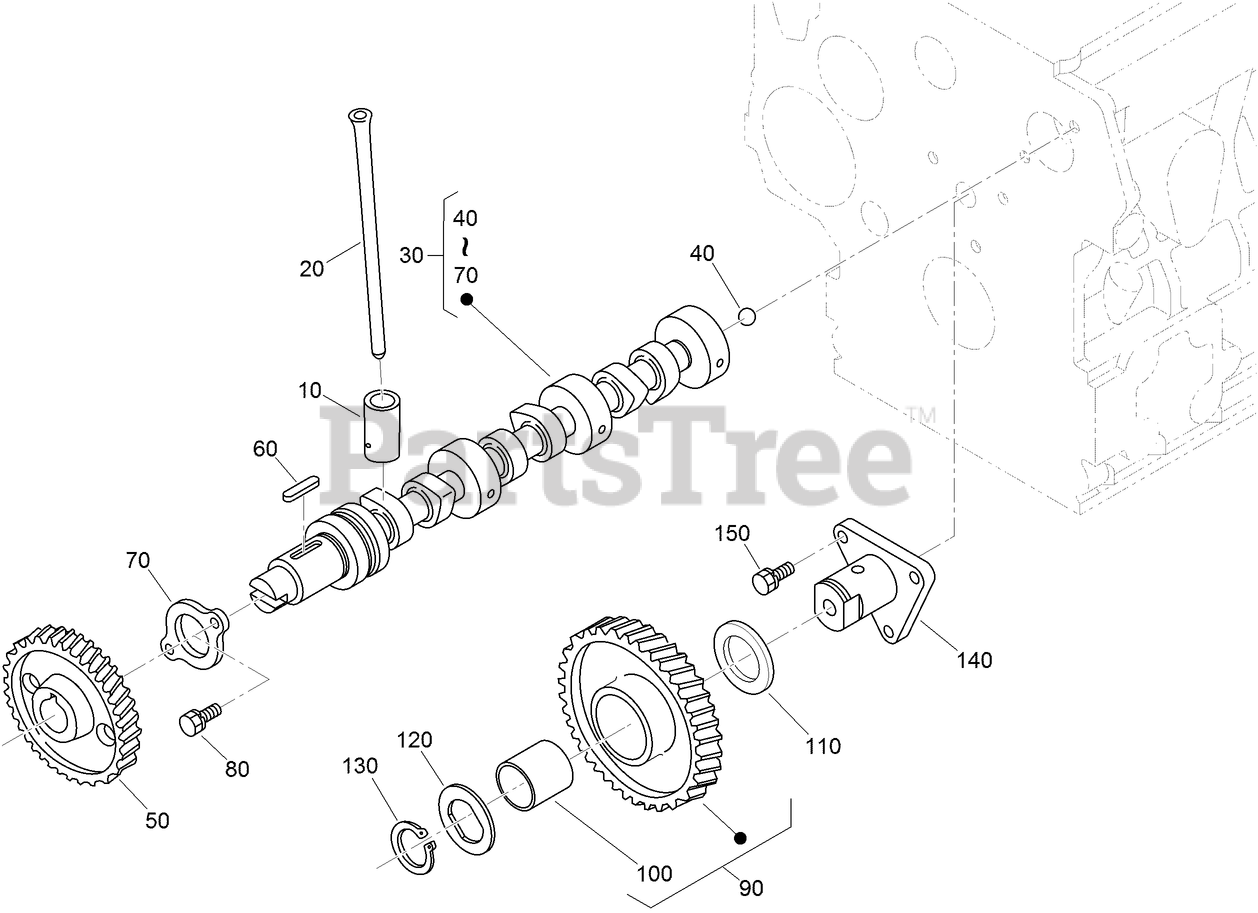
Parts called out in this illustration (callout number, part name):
10	TAPPET
20	ROD-PUSH
30	CAMSHAFT ASM
50	GEAR-CAM
60	KEY-FEATHER
70	STOPPER (CAMSHAFT)
90	IDLER GEAR ASM
100	BUSHING-GEAR, IDLE
110	COLLAR-GEAR, IDLE
120	COLLAR-GEAR, IDLE
130	CIRCLIP-GEAR, IDLE
140	SHAFT-GEAR, IDLE
